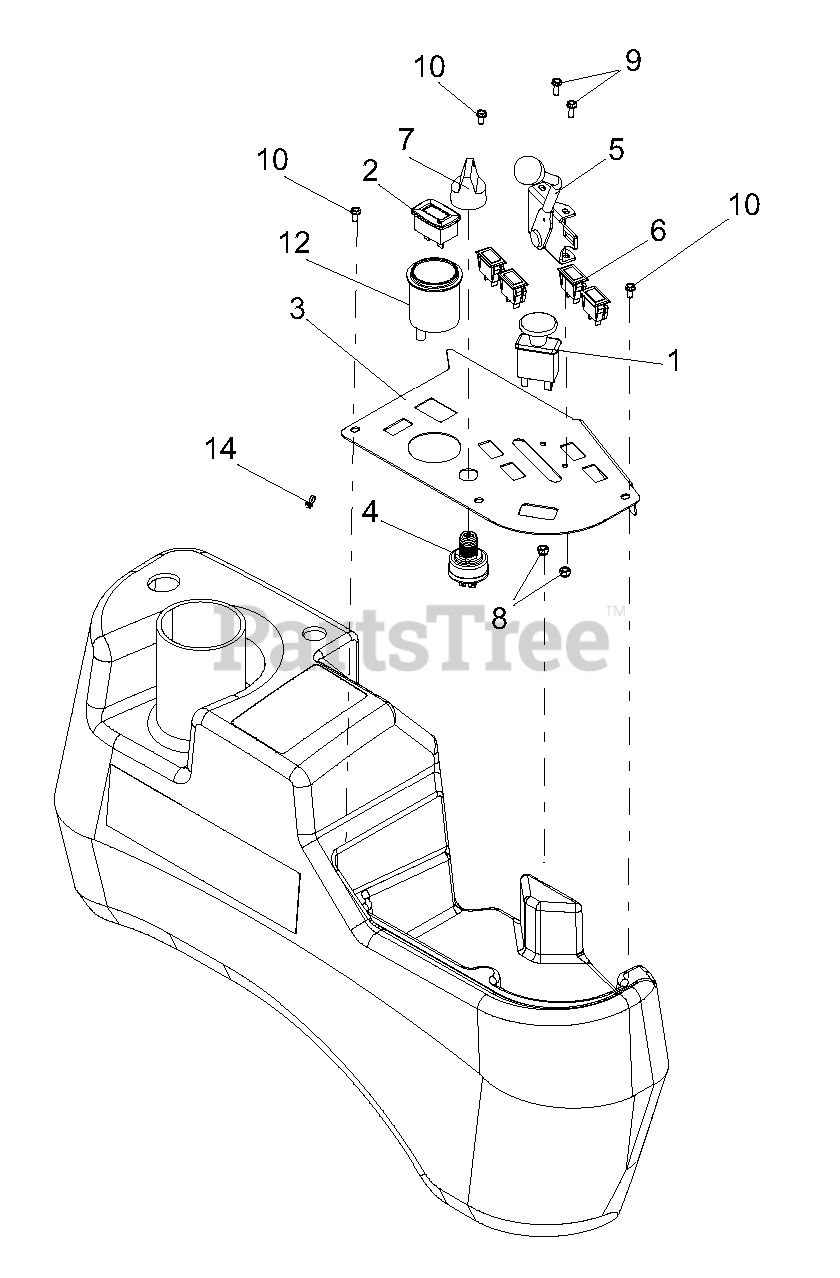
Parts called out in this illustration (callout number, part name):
1	SWITCH, CLUTCH
2	METER, HOUR W/MAINTENANCE
3	PANEL, CONTROL PM 200 DIESEL
4	SWITCH, IGNITION
5	CABLE, PRO-CONTROL THROTTLE
6	LIGHT, INDICATOR
7	KEY, W/ COVER
8	NUT-LK-NYL #10-24 YWZC
9	SCR-MCH 10-24X.50 HWH YWZC
10	SCR, HWH 10-24x.38 STAINLESS
12	GAUGE, TEMP
